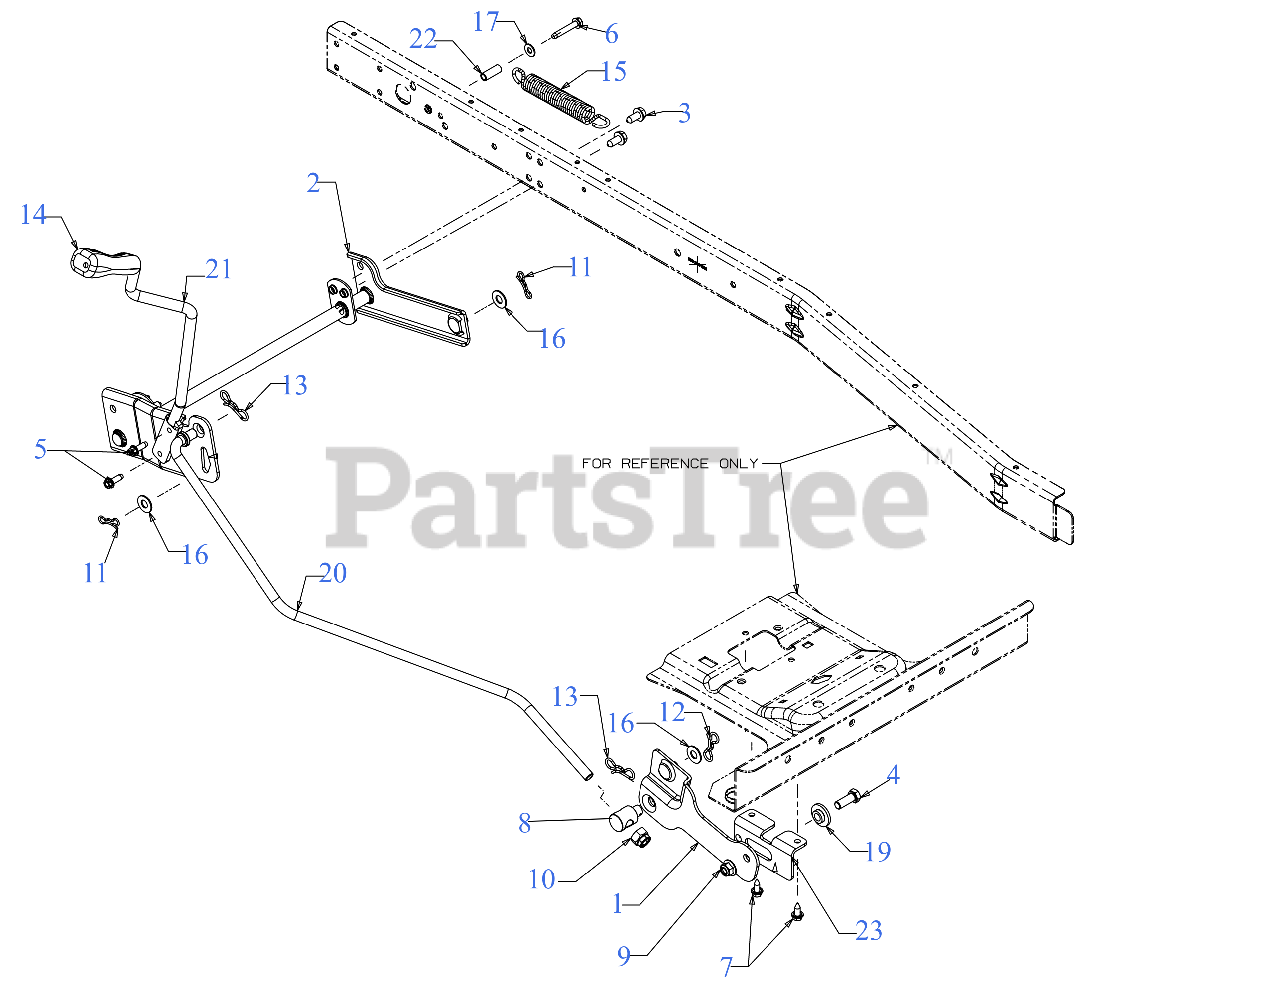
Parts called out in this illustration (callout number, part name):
1	BRACKET ASSEMBLY (POWDER BLACK)
2	LIFT SHAFT ASSEMBLY (POWDER BLACK)
3	SCREW 5/16-18 x .750
4	SCREW 3/8-16 x 1 GR5
5	SCREW 1/4-20 x .750
6	SCREW 1/4-20 x 1.50"
7	SCREW 1/4-20X.625
11	BOW TIE COTTER PIN 1/4-5/16
12	PIN:COTTER
13	BOW TIE COTTER PIN
14	HANDLE GRIP
15	EXTENSION SPRING .85 x 5.91
16	FLAT WASHER.40 ID
17	FLAT WASHER
19	SHOULDER SPACER
21	DECK LIFT ROD
